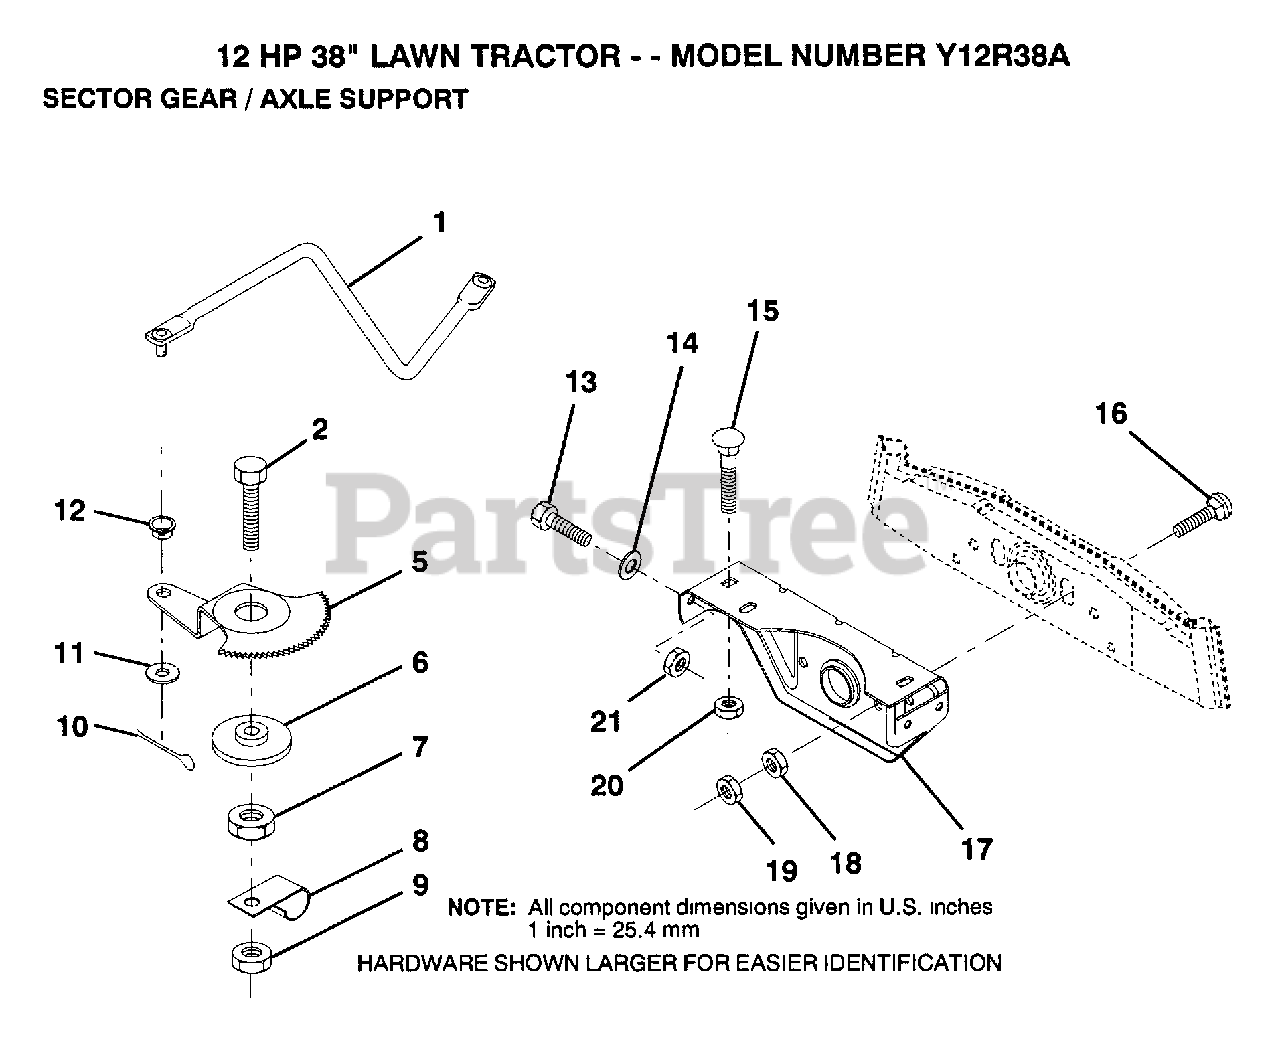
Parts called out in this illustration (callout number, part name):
1	DRAG LINK
2	"BOLT,HEX"
5	GEAR SECTOR
6	BUSHING
7	NUT
8	CLIP INSULATOR
9	NUT LTV
10	COTTER PIN
11	WASHER
12	BUSHING.DRAGLINK
13	BOLT
14	WASHER
15	BOLT
16	BOLT
17	"SUPT,FRT AXLE"
18	NUT.HEX.3/8-16UNC
19	LOCKNUT
